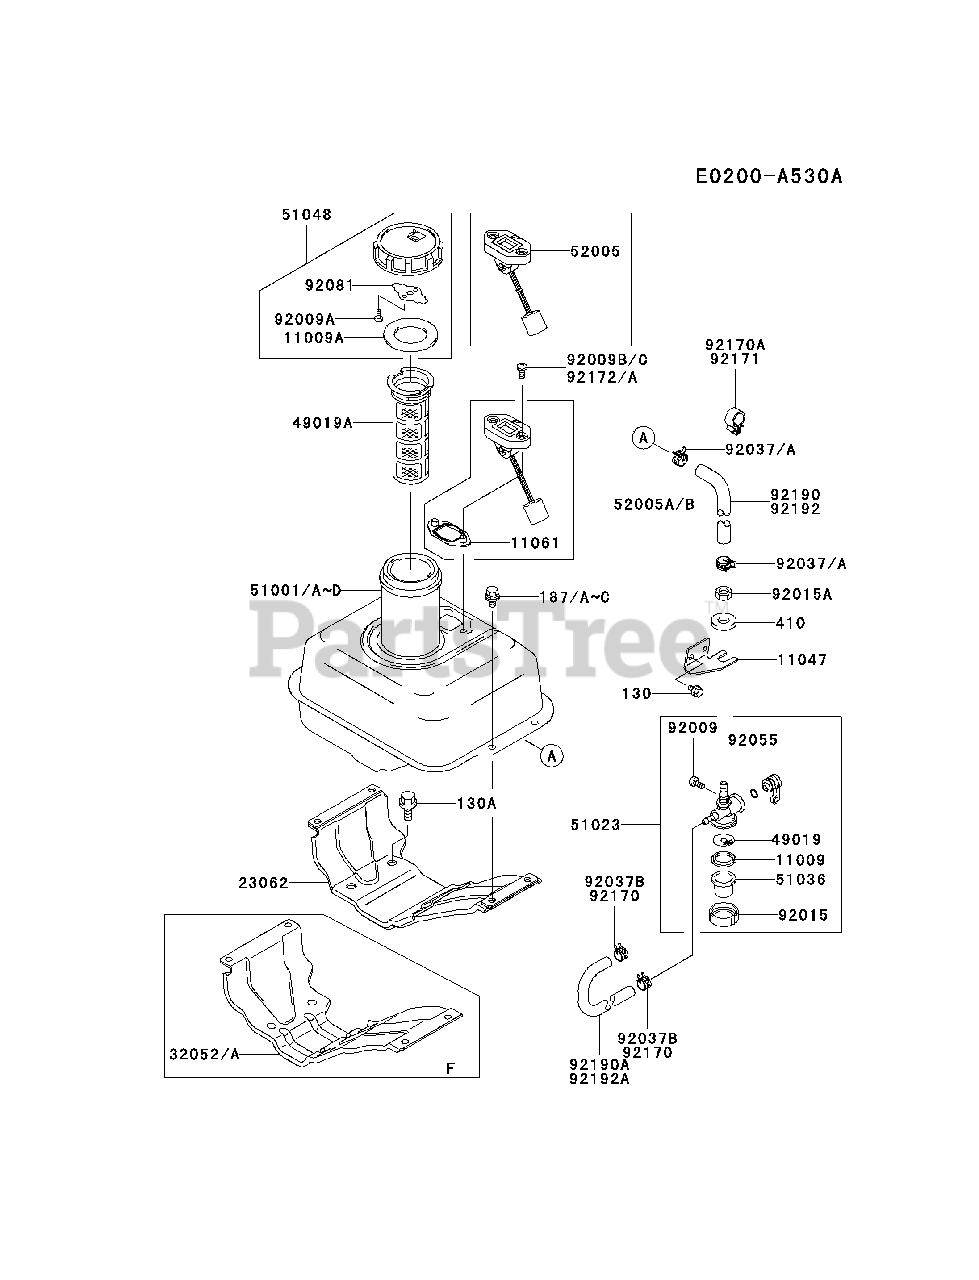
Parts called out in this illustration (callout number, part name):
130	BOLT-FLANGED
130A	BOLT-FLANGED
187B	BOLT-UPSET-WSP
410	W-PLAIN-S
